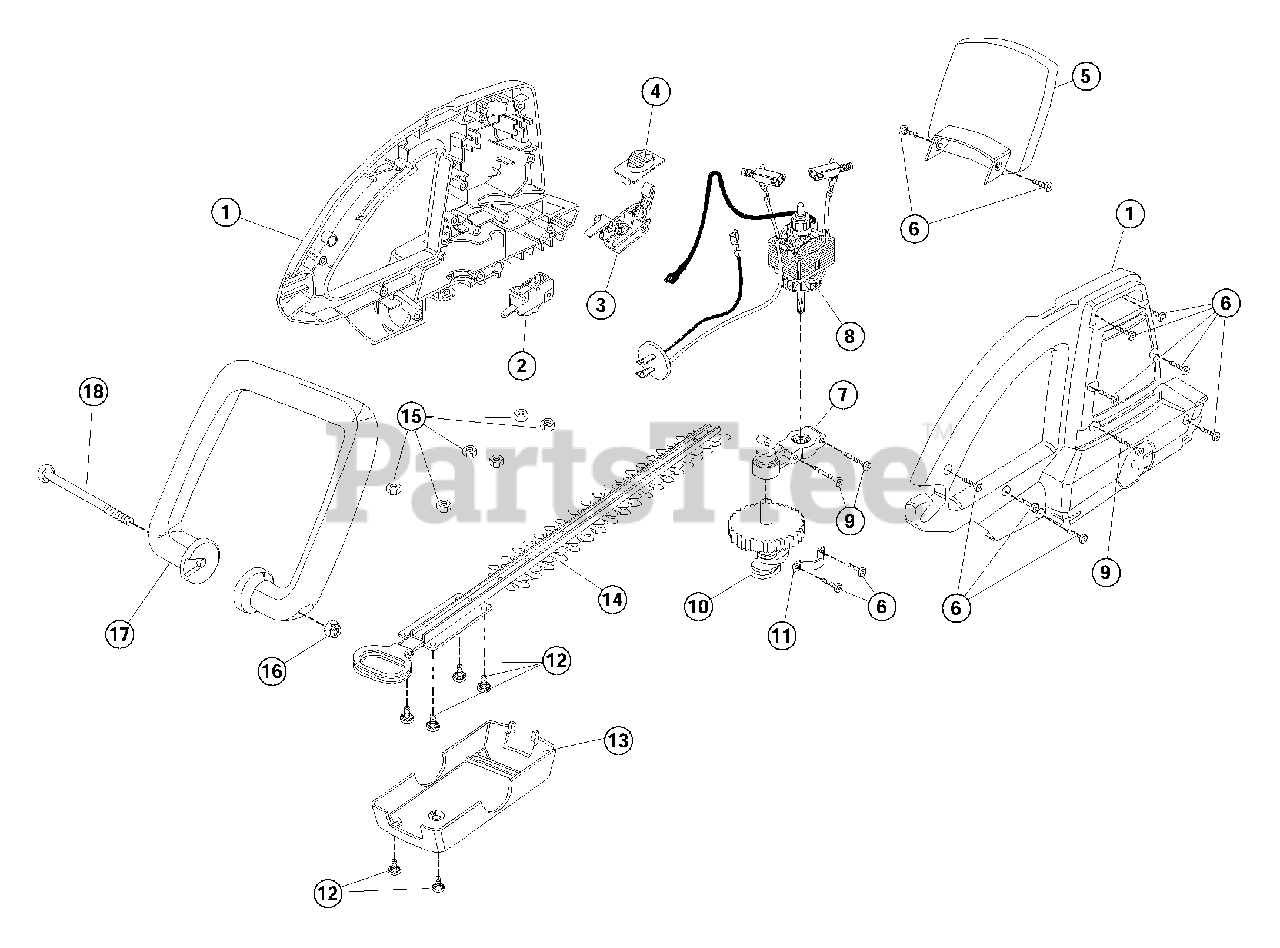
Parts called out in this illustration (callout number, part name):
1	Housing Assembly
3	Switch Trigger Assembly
4	Lock-On Button
5	Blade Guard
7	Bearing Plate w/Bearings
10	Gear Assembly
11	Bearing Strap
13	Blade Cover
14	Blade Assembly
15	Hex Nut (8-32)
16	Hex Nut (1/4-20)
17	Front Handle
